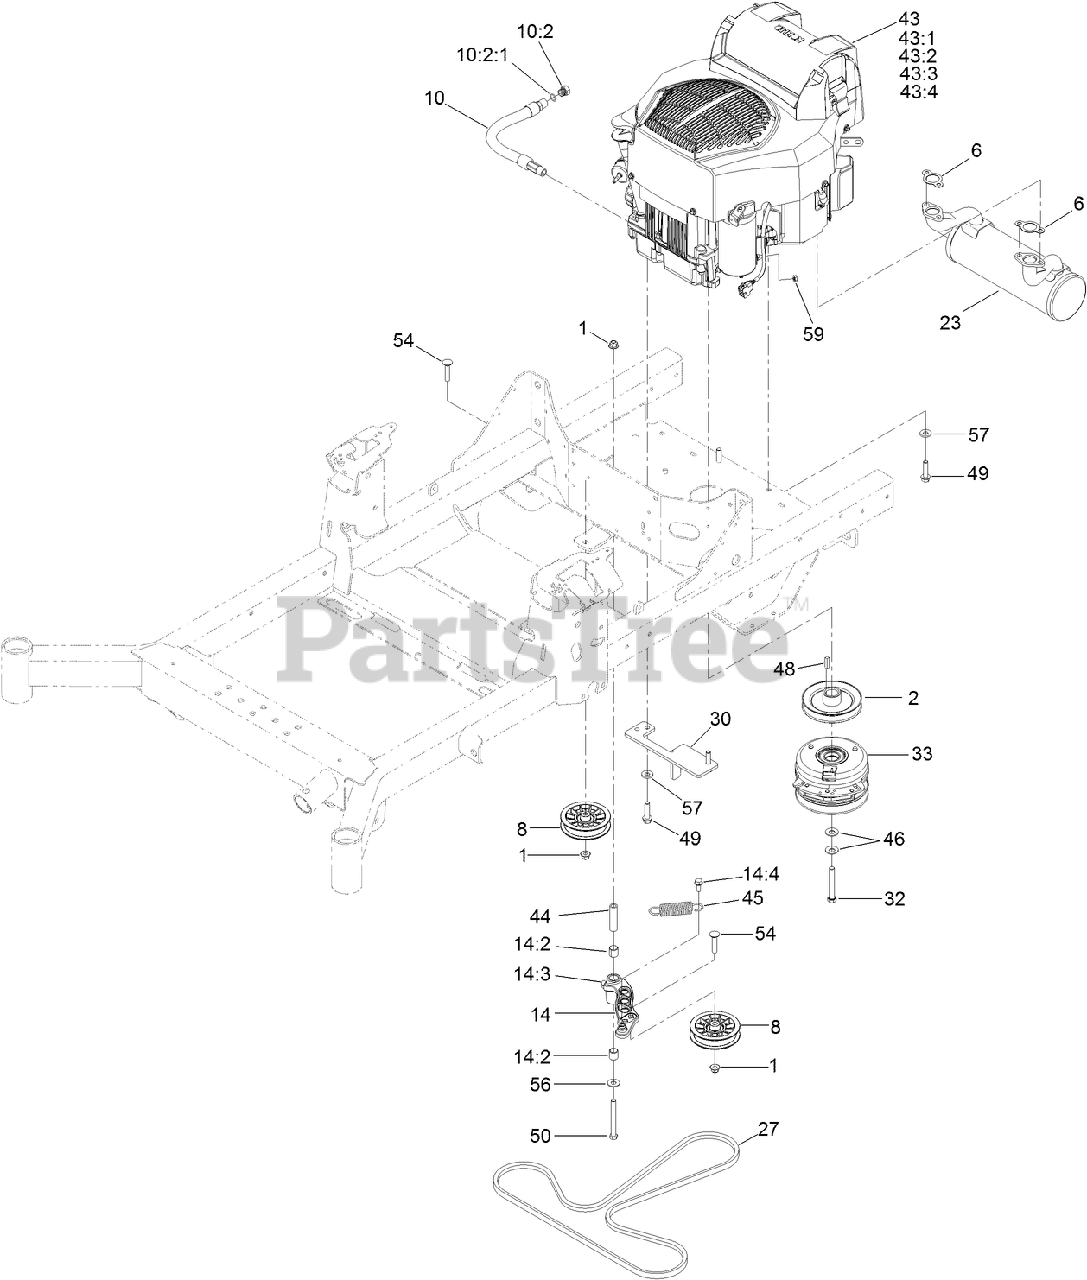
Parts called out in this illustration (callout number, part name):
1	NUT-HF, NI
2	SHEAVE-SPLIT STEEL
6	GASKET-EXHAUST
8	PULLEY-FLAT
10	OIL DRAIN HOSE ASM
10:2	PLUG-HH
10:2:1	O-RING
14	IDLER ARM ASM
14:2	SLEEVE-BEARING
14:3	FITTING-GREASE, 90 DEG
14:4	SCREW-HWHTF
23	MUFFLER-KOHLER AES
27	BELT-V
30	ANCHOR-CLUTCH
32	SCREW-HH W/LOCTITE
33	CLUTCH-PTO
43:1	KOHLER 16 083 01-S ENGINE AIR FILTER
43:2	KOHLER 52 050 02-S ENGINE OIL FILTER
43:3	KOHLER 24 050 13-S FUEL FILTER
43:4	KOHLER 25 083 04-S SAFETY FILTER
44	BUSHING-PIVOT, IDLER
45	SPRING-EXTENSION
46	WASHER-SPRING
49	SCREW-HWH
50	SCREW-HH
54	SCREW-CARR
56	WASHER-FLAT
57	WASHER-BELLEVILLE
59	NUT-HF
